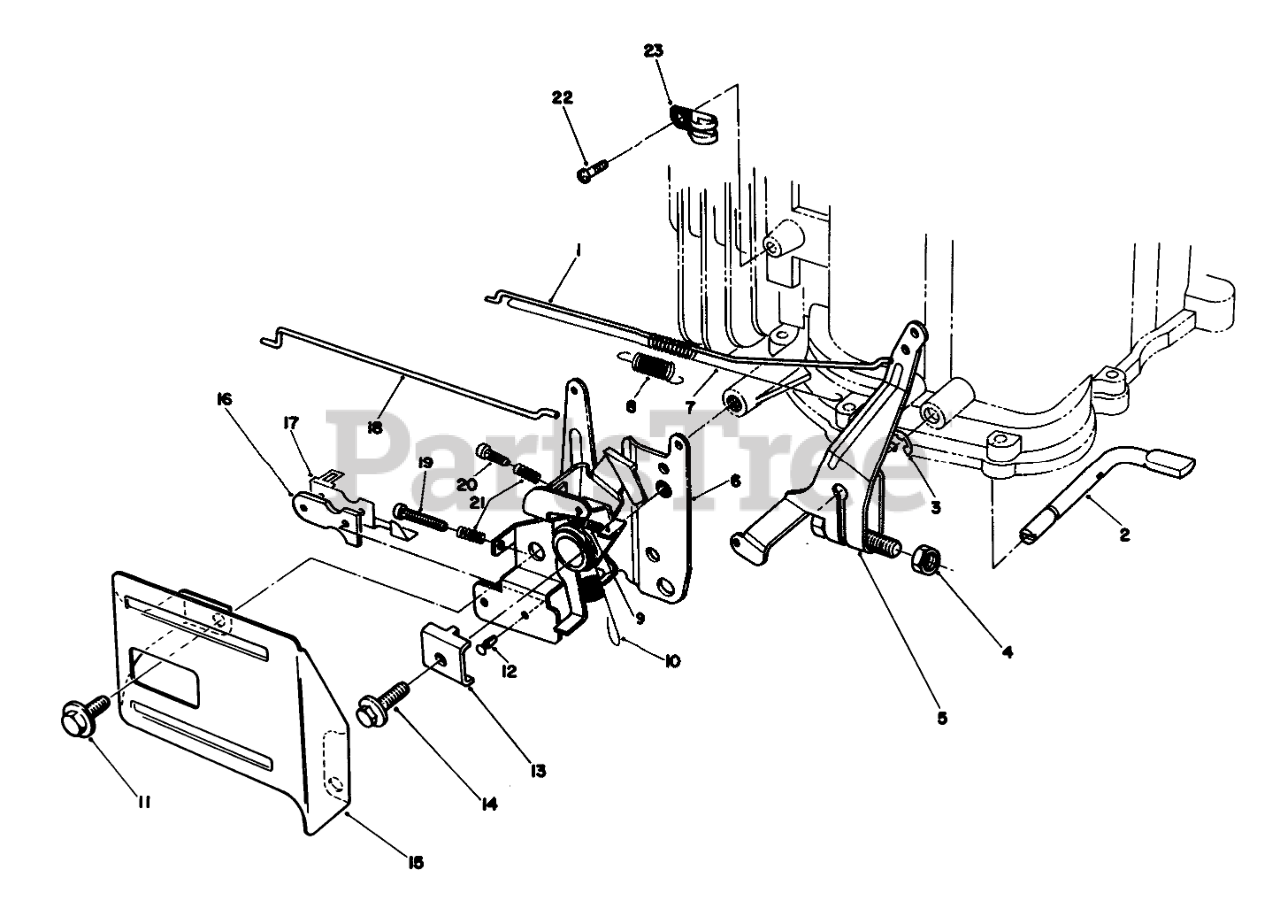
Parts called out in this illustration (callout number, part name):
1	Rod-Carburetor
2	SHAFT
3	E-RING
5	ARM ASM
6	THROTTLE
7	SPRING
8	SPRING
9	SPRING
10	SPRING
12	RIVET
13	CLAMP-CABLE
15	THROTTLE GUARD
16	INSULATOR-KILL SWITCH
17	TERMINAL-KILL SWITCH
18	Rod-Choke
19	SCREW
20	SCREW
21	SPRING
22	SCREW
23	Clamp
